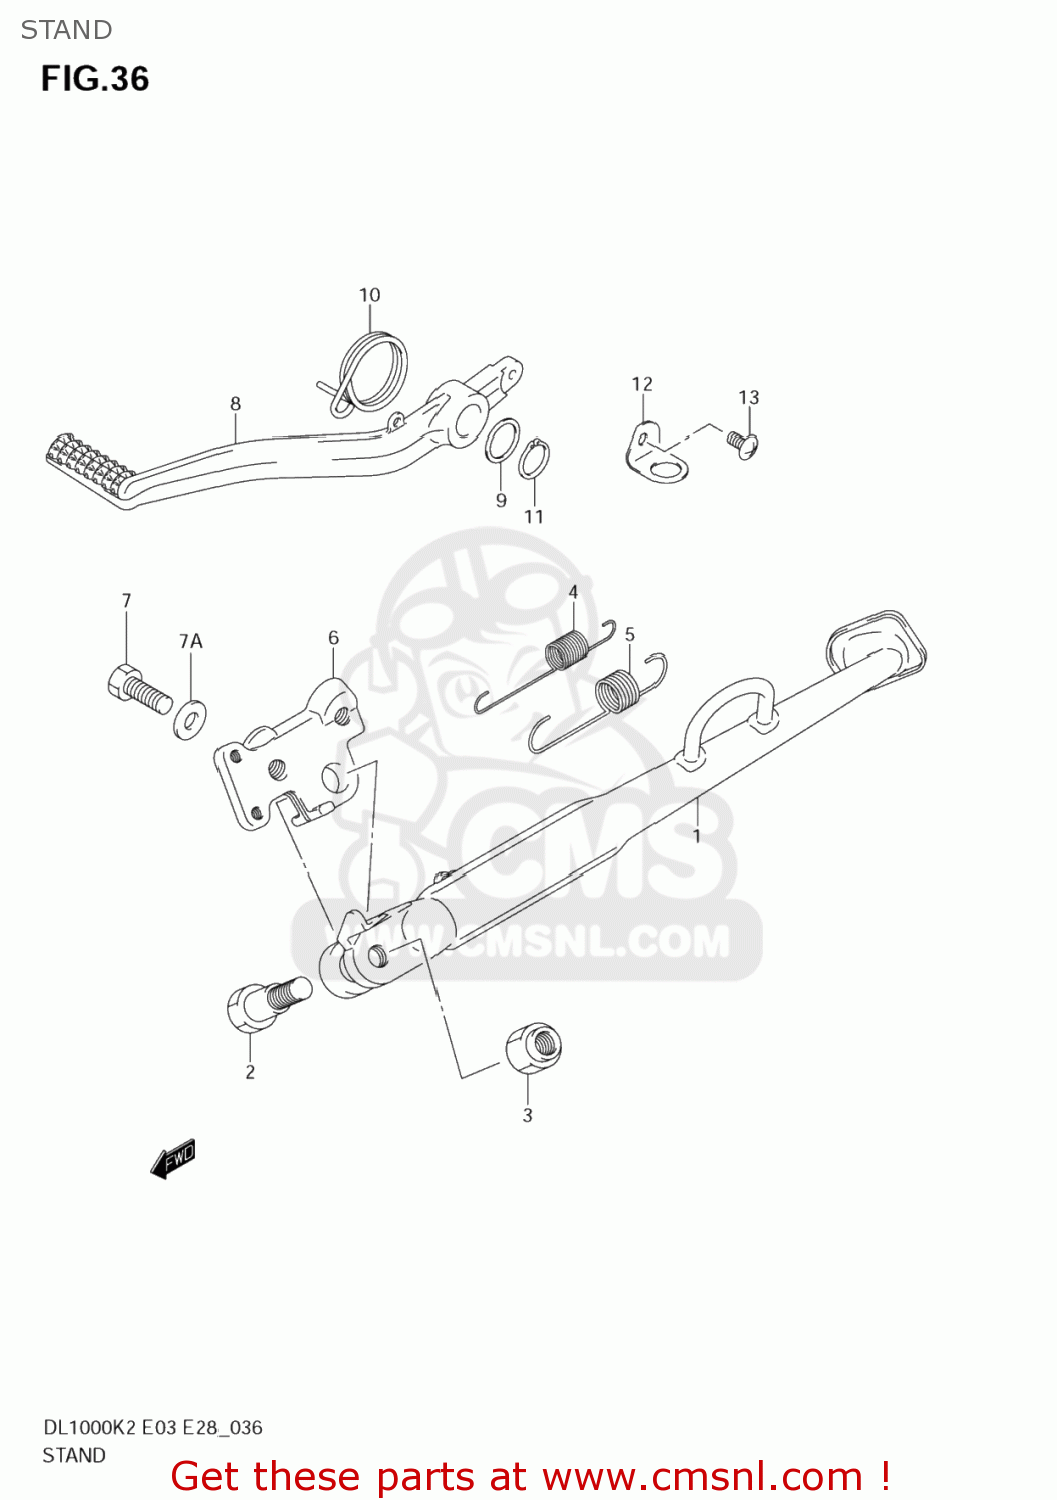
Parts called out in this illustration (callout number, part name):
1	STAND,PROP
2	BOLT(10X37.5)
3	NUT,PROP STAND
4	SPRING
5	SPRING
6	BRACKET, PROP STAND
7	BOLT(12X30)
7A	WASHER(12.5X24X2.6)
8	PEDAL,BRAKE
9	WASHER(18X24X1)
10	SPRING
11	CLIP
12	BRACKET,STOP LAMP SWITCH
13	SCREW 6X12
